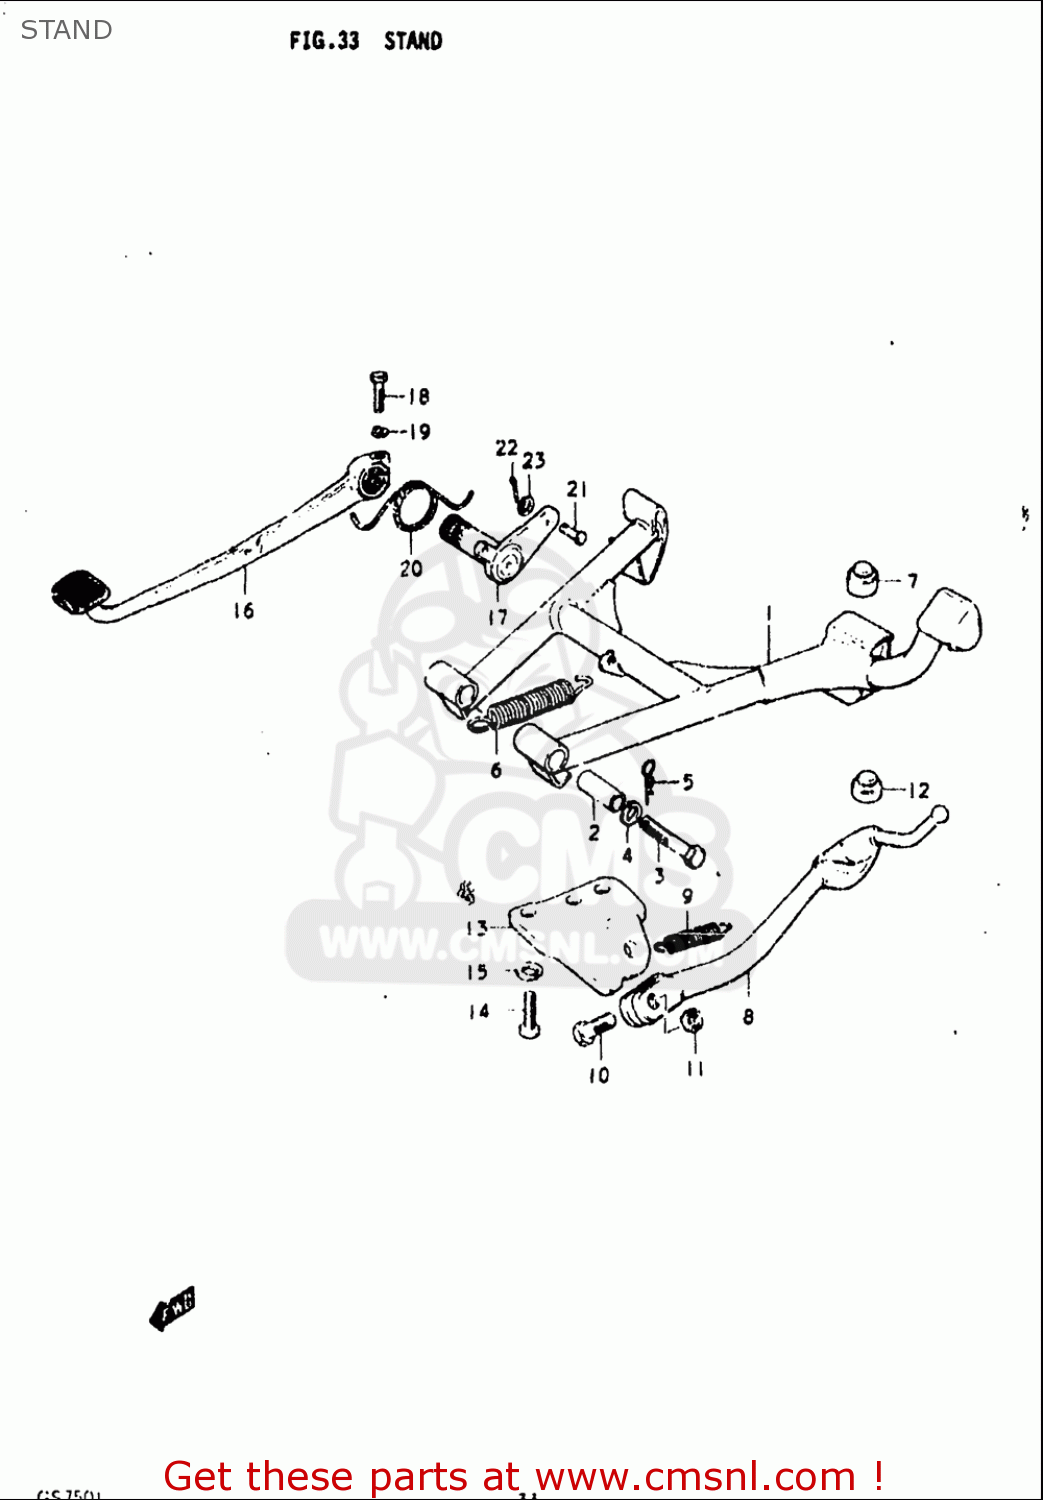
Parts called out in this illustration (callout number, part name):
2	SPACER(10X16X38.8)
3	BOLT(10X65)
4	WASHER,LOCK
5	CLIP
6	SPRING
7	CUSHION
8	STAND,PROP
9	SPRING
10	BOLT(10X30)
11	NUT
12	CUSHION
14	BOLT(10X27)
15	WASHER,LOCK
17	ARM,BRAKE PEDAL ROD
18	BOLT
19	WASHER,LOCK
20	SPRING
21	PIN
22	PIN
23	WASHER
